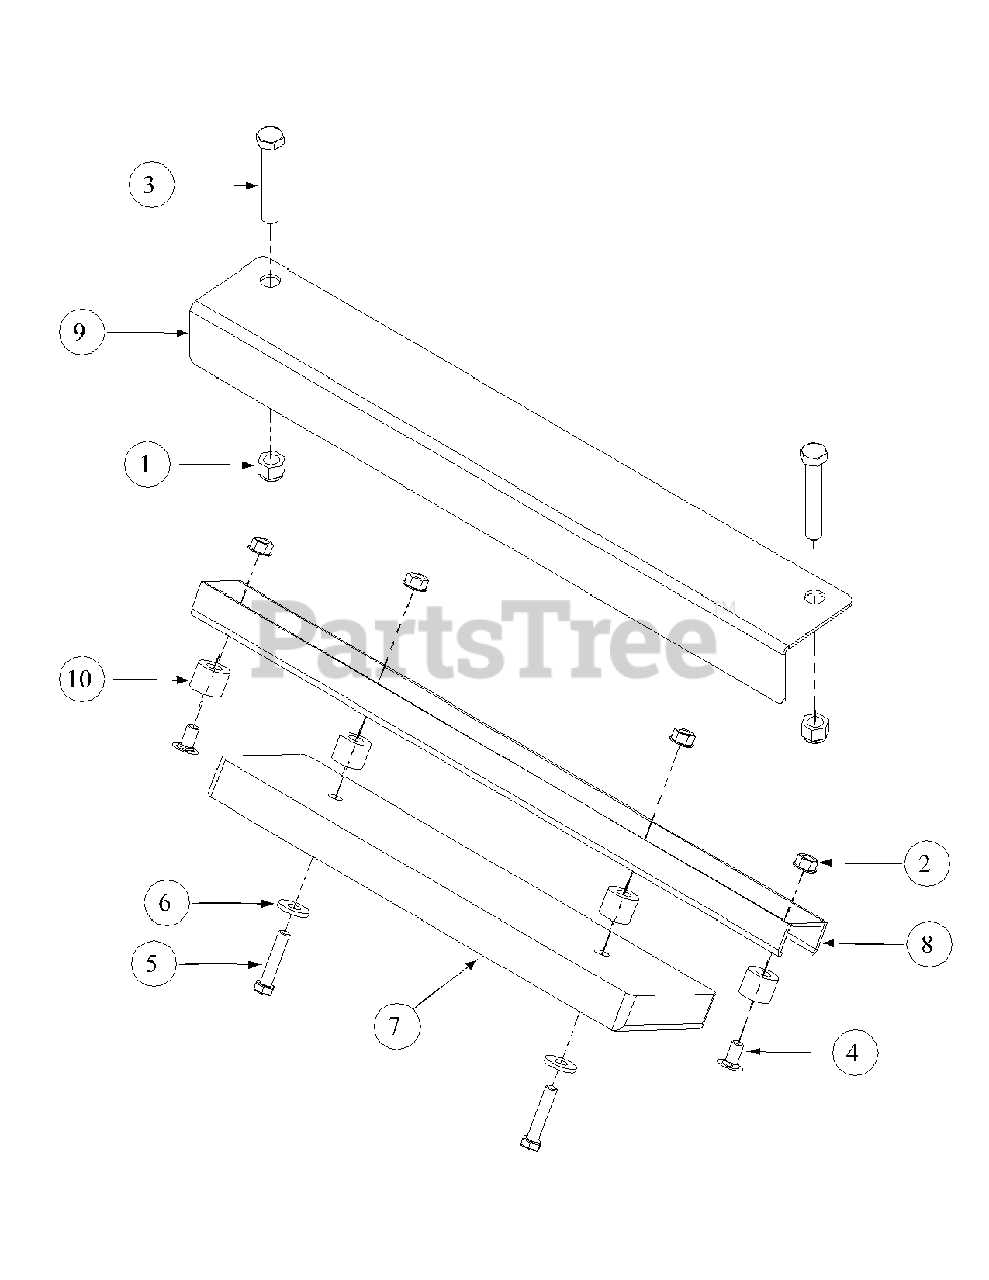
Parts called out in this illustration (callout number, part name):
1	Hex Nut, 1/2-13, Insert Lock
2	Nut, Hex 3/8-16 Flange Lock
3	HHCS, 1/2-13, 3.00
4	Carriage Bolt, 3/8-16 x 1.75
5	Hex Cap Screw,3/8-16, 3.00
6	Flat Washer, .406 ID x 1.0 OD x .105
8	Bumper Cross Bar
9	Rear Bumper Bracket
10	Spacer.635 ID x .86 LG
